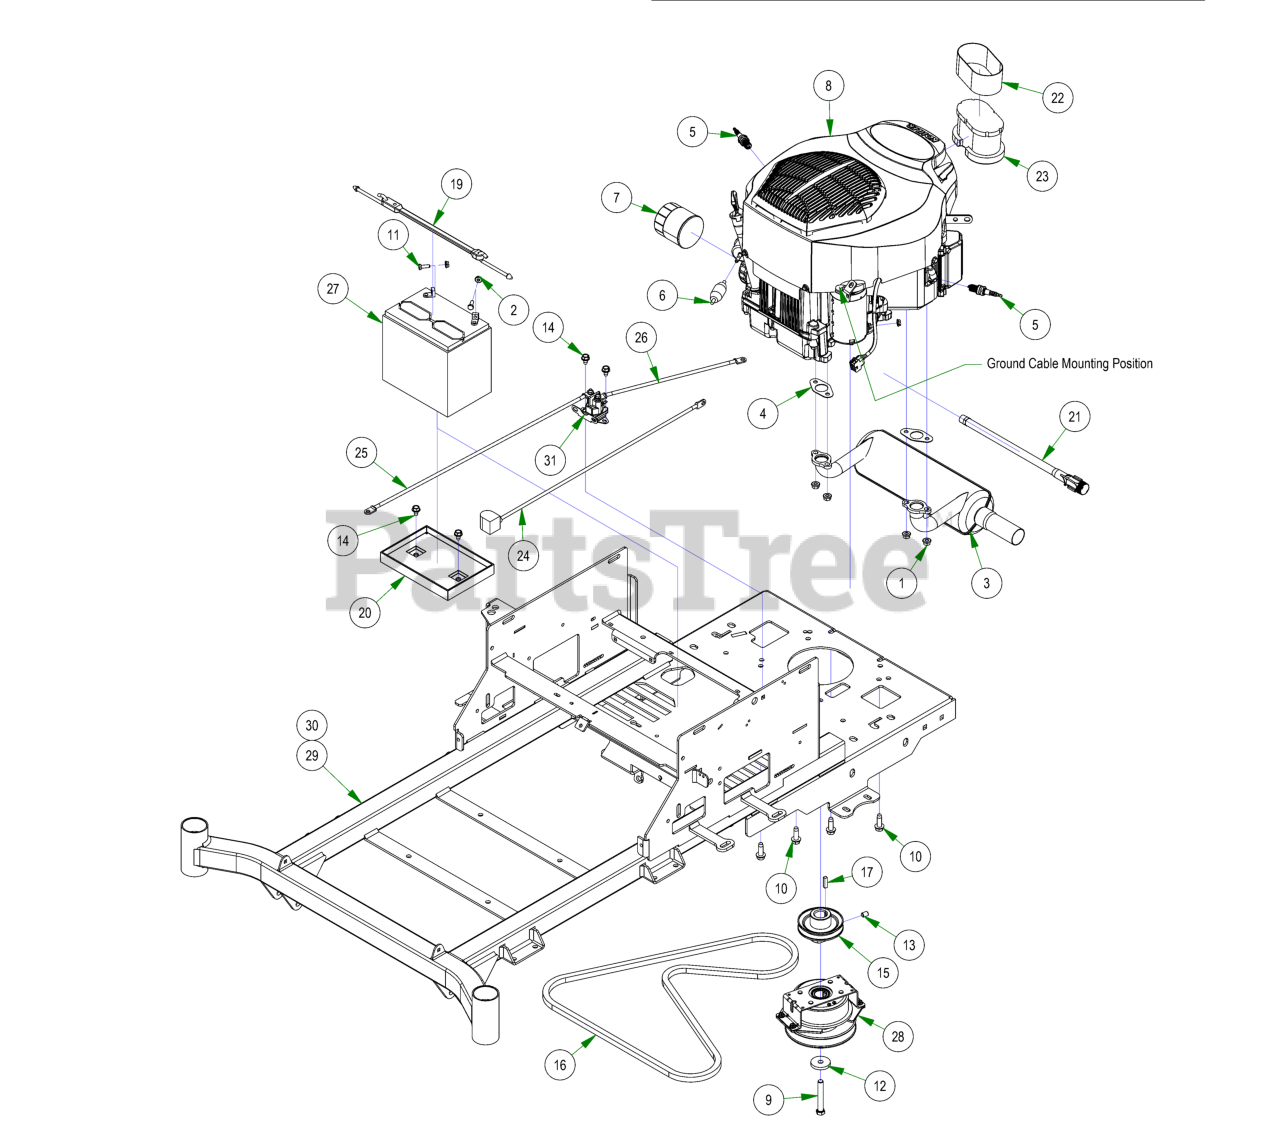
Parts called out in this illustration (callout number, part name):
1	M8 Nut Connects the 015-1012-00 and the 015-8240-00
2	1/4-20 HEX SERRATED FLANGE NUT HARD/ZINC
3	Kohler Muffler
4	Exhaust Gasket
5	Spark Plug
6	25/26 HP Kohler Fuel Filter
7	25 HP Kohler Oil Filter ZT?MZ
8	KT745 Kohler Engine
9	7/16-20x3” Hex Bolt GR 8 W/ Patch
10	3/8-16 X 1-1/8 HEX WASHER UNSLOT SERRATED (TRI-LOB) TRS ZINC YELLOW
11	1/4-20 X 3/4 HEX CAP SCREW (GR.5) ZINC
12	CLUTCH WASHER
13	3/8-16 X 1/2 SOCKET SET SCREW (CUP PT) PLAIN
14	5/16-18 X 1/2 HWH unslot (F) tcs zinc
15	3-3/4" Motor Pulley
17	1/4 X 1 SQ MACHINERY KEY 1018 STL PLN
18	2023 Battery Hold Down Assembly
19	2023 Rubber Battery Hold Down Strap
20	Battery Tray
21	Kohler Oil Drain
24	24 inch Black Cable – MZ/ZT
25	24" Red Battery Cable
26	12 in red battery cable
27	SP-35 Battery
29	2024 MZ 42-48 Frame
30	2024 MZ-Avenger 54-60 Frame
